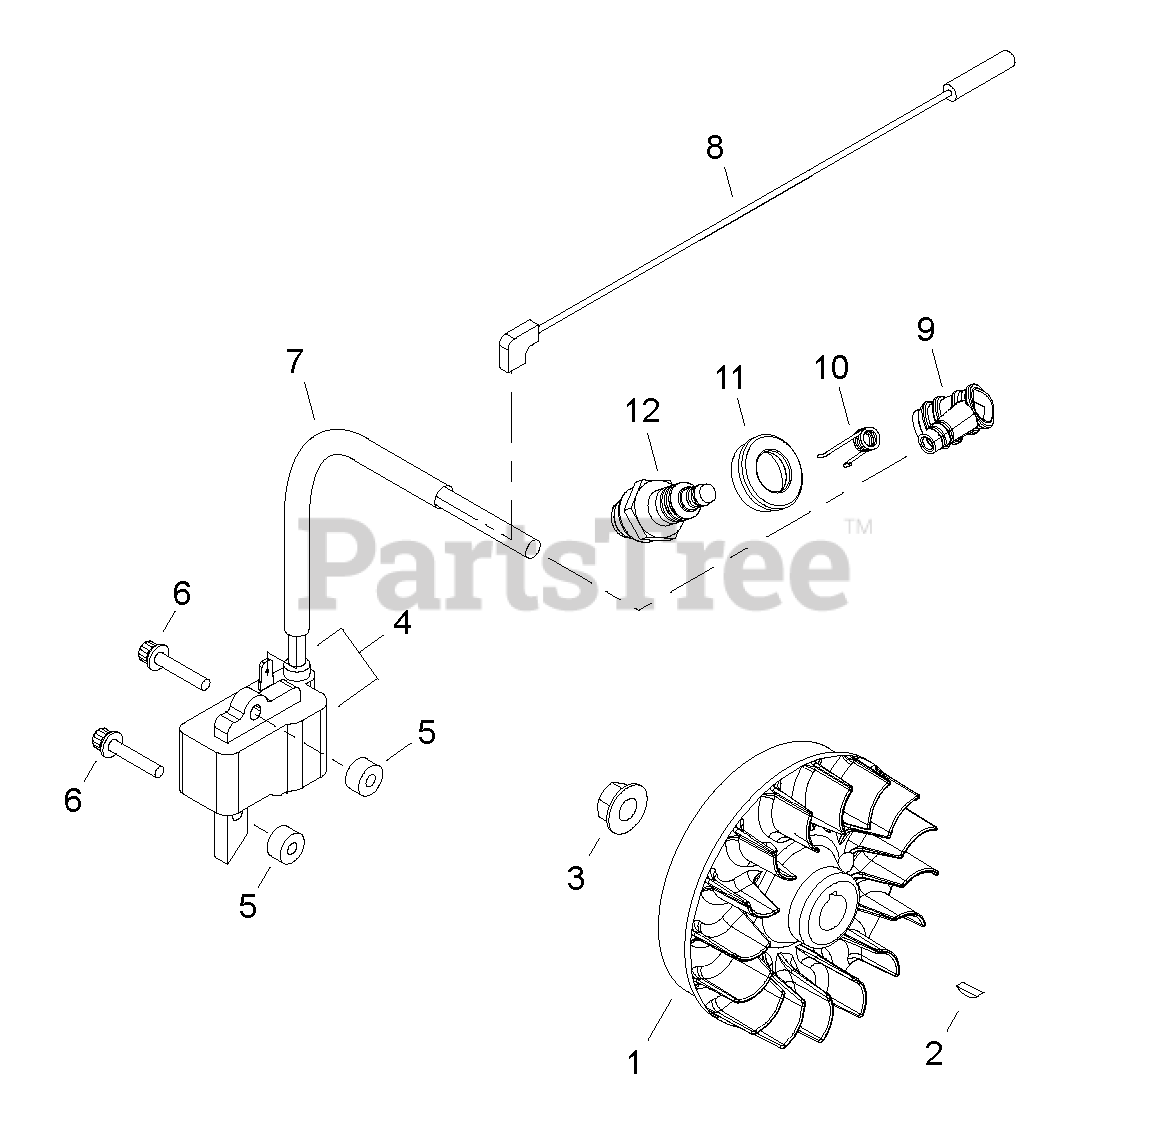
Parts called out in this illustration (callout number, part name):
1	FLYWHEEL
2	KEY - 3X10
3	NUT - 8
4	COIL, IGNITION
5	INSULATOR
6	SCREW - 4X20
7	TUBE
8	LEAD - IGNITION
9	CAP, SPARK PLUG
10	TERMINAL, SPARK PLUG CAP
11	SEAL, DUST
12	SPARK PLUG -- BPMR-6A
